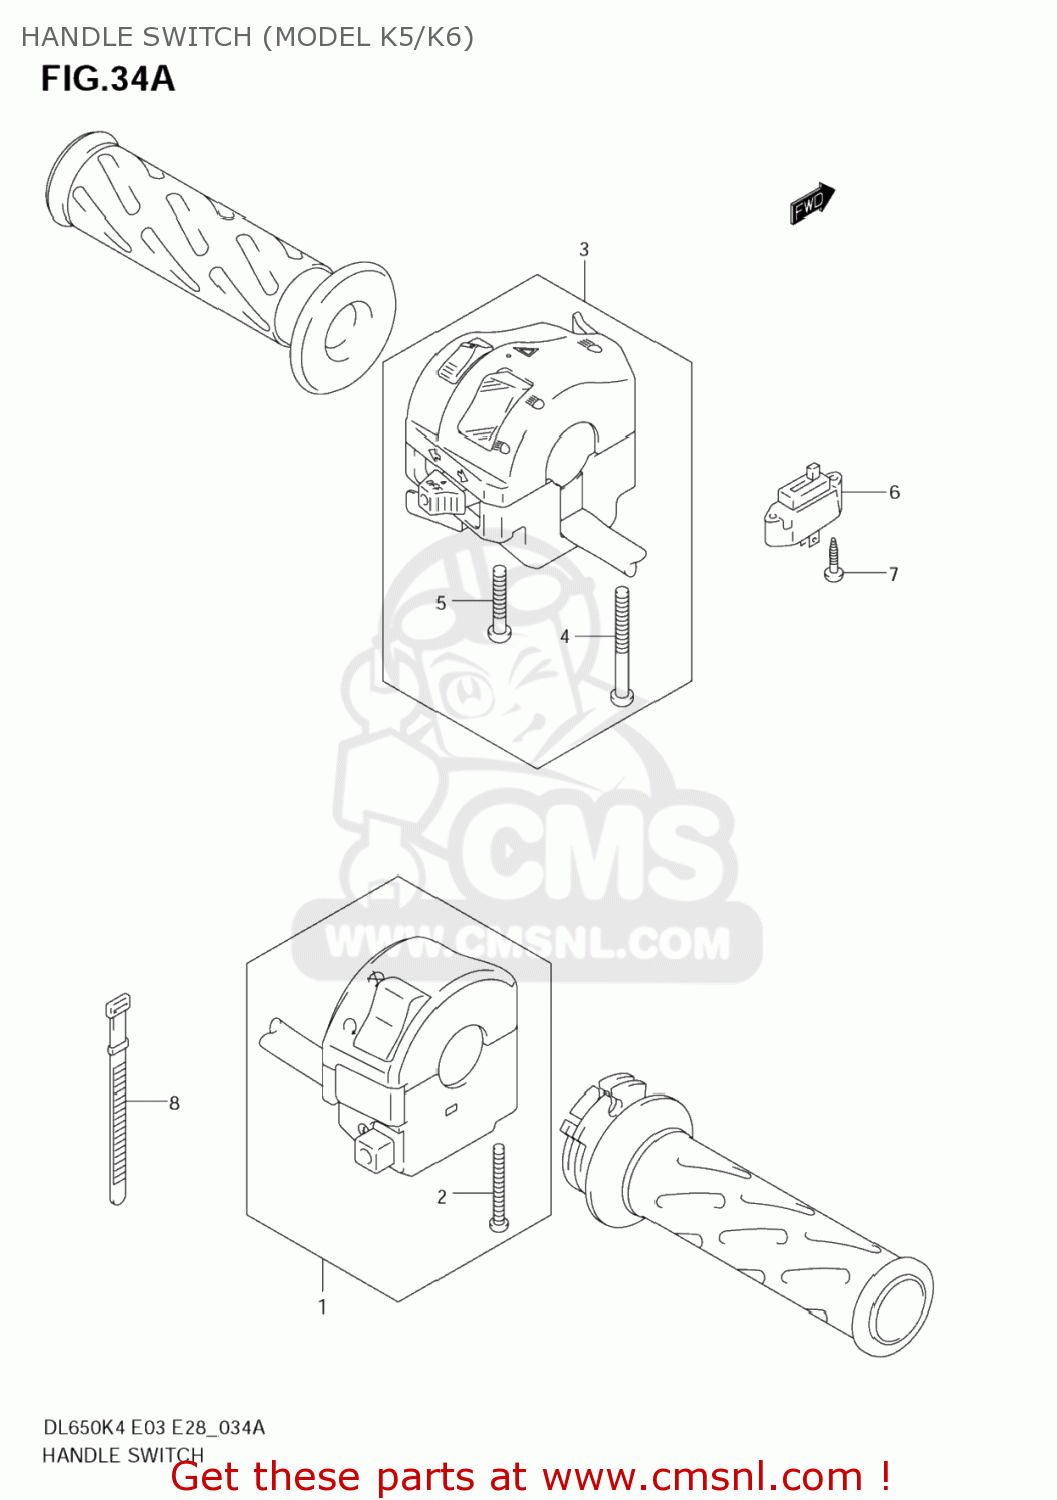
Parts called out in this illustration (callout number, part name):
1	SWITCH ASSY,HANDLE,R
2	SCREW
3	SWITCH ASSY,HANDLE,L
4	SCREW
5	SCREW
6	SWITCH ASSY,CLUTCH
7	SCREW(3X14)
8	CLAMP(L:120)
